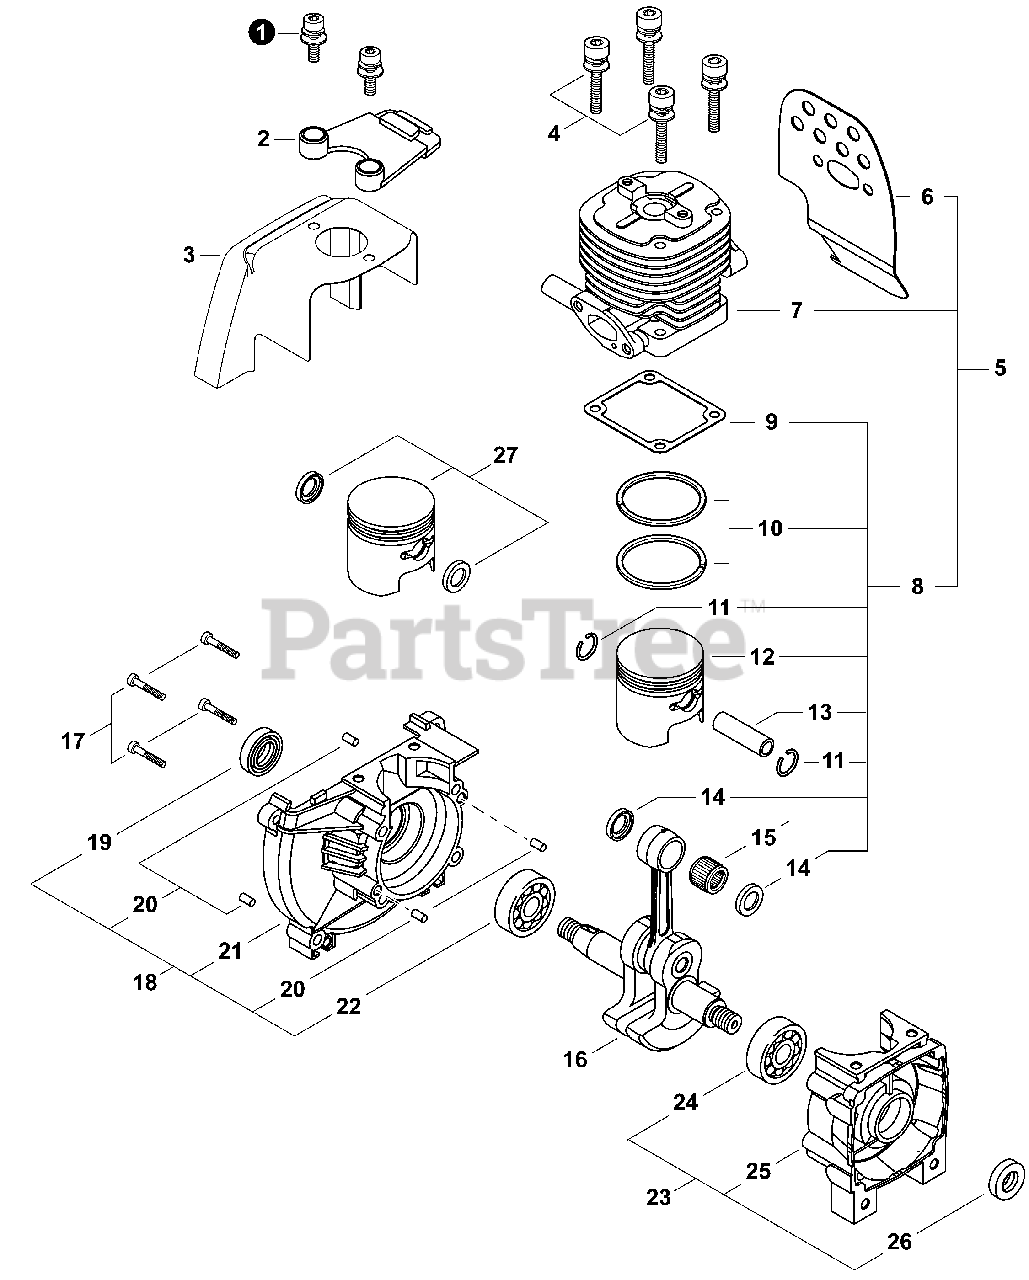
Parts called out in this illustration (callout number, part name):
1	BOLT M5×18
2	STAY, ENGINE COVER
3	COVER, ENGINE
4	BOLT M5×25
5	REBUILD KIT - ENGINE
6	HEAT SHIELD, EXHAUST
7	CYLINDER
8	PISTON KIT
9	GASKET, CYLINDER
10	RING, PISTON
11	RING, SNAP
12	PISTON
13	PIN, PISTON
14	WASHER, THRUST 11
15	BEARING, NEEDLE 11
16	CRANKSHAFT ASSY
17	BOLT 5×30
18	CRANKCASE ASSY, M
19	SEAL, OIL 16
20	PIN, LOCATING 5×10
21	CRANKCASE M
22	BEARING, BALL 6202 C3
23	CRANKCASE ASSY, S
24	BEARING, BALL 6202 C3
25	CRANKCASE S
26	SEAL, OIL 16
27	PISTON SET
